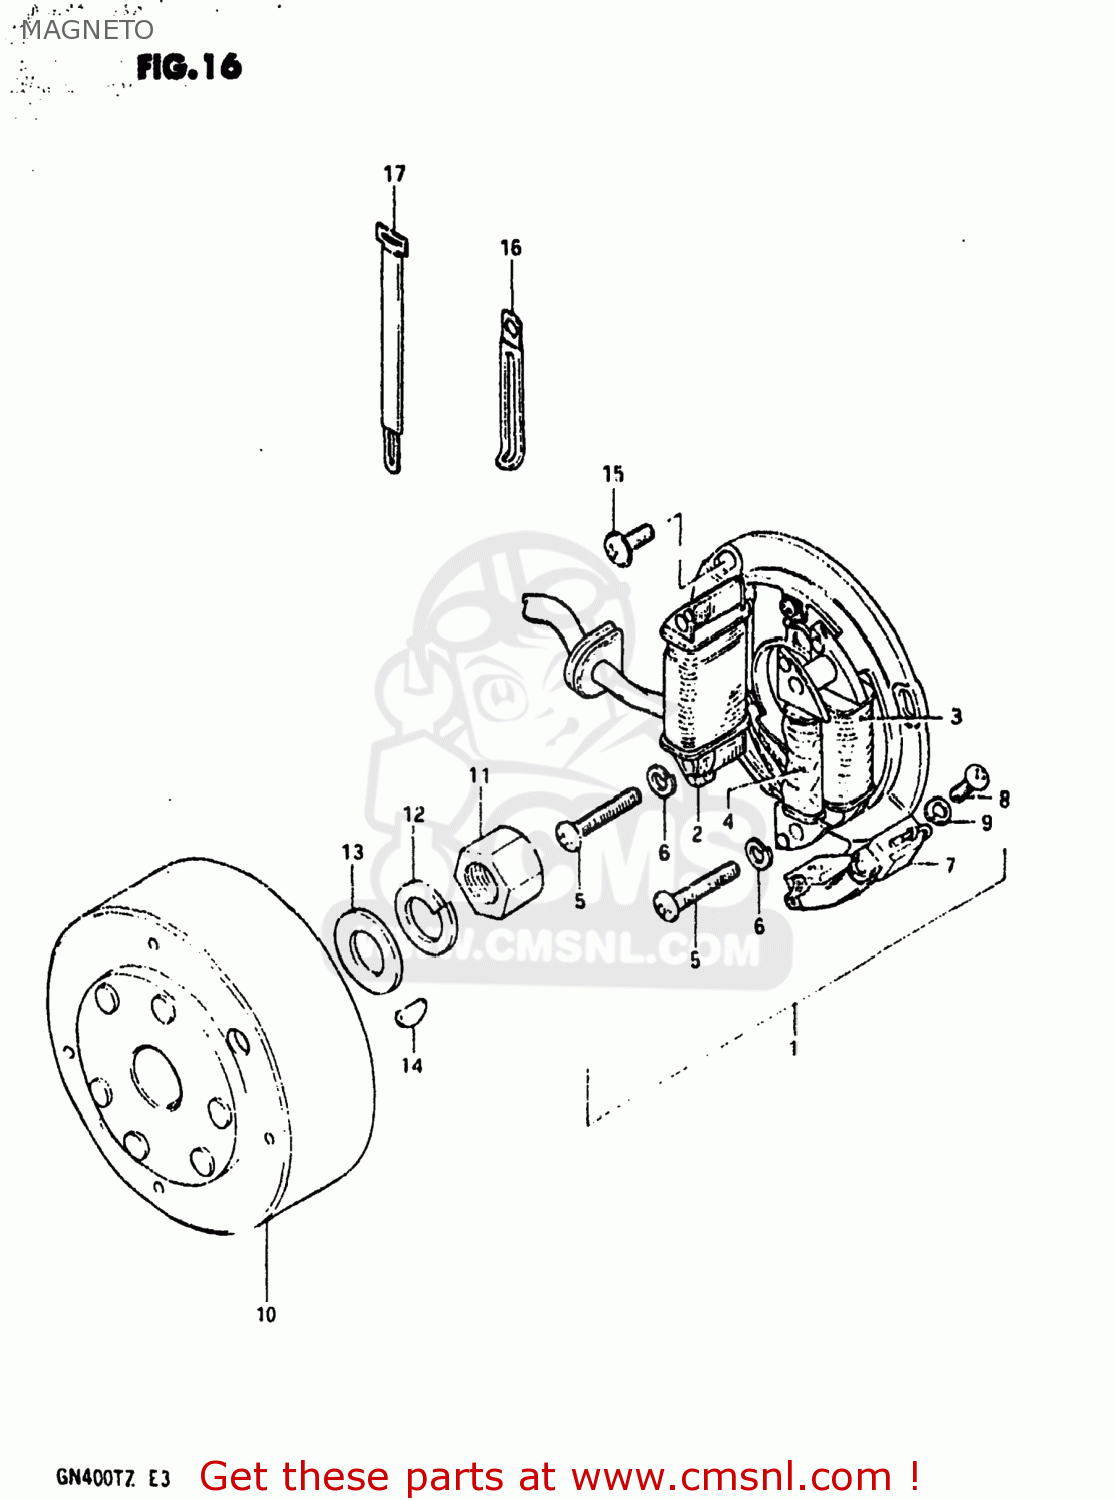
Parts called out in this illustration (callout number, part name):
1	STATOR ASSEMBLY
2	COIL,LIGHTING
3	COIL,PRIMARY
4	COIL,PULSER
5	SCREW
6	LOCK WASHER
7	COIL,PULSER
8	SCREW
9	LOCK WASHER
10	ROTOR,FLYWHEEL
11	NUT
12	LOCK WASHER
13	WASHER(14X27X3)
14	KEY 4MM
15	SCREW(5X14)
16	CLAMP
17	CLAMP L:110
